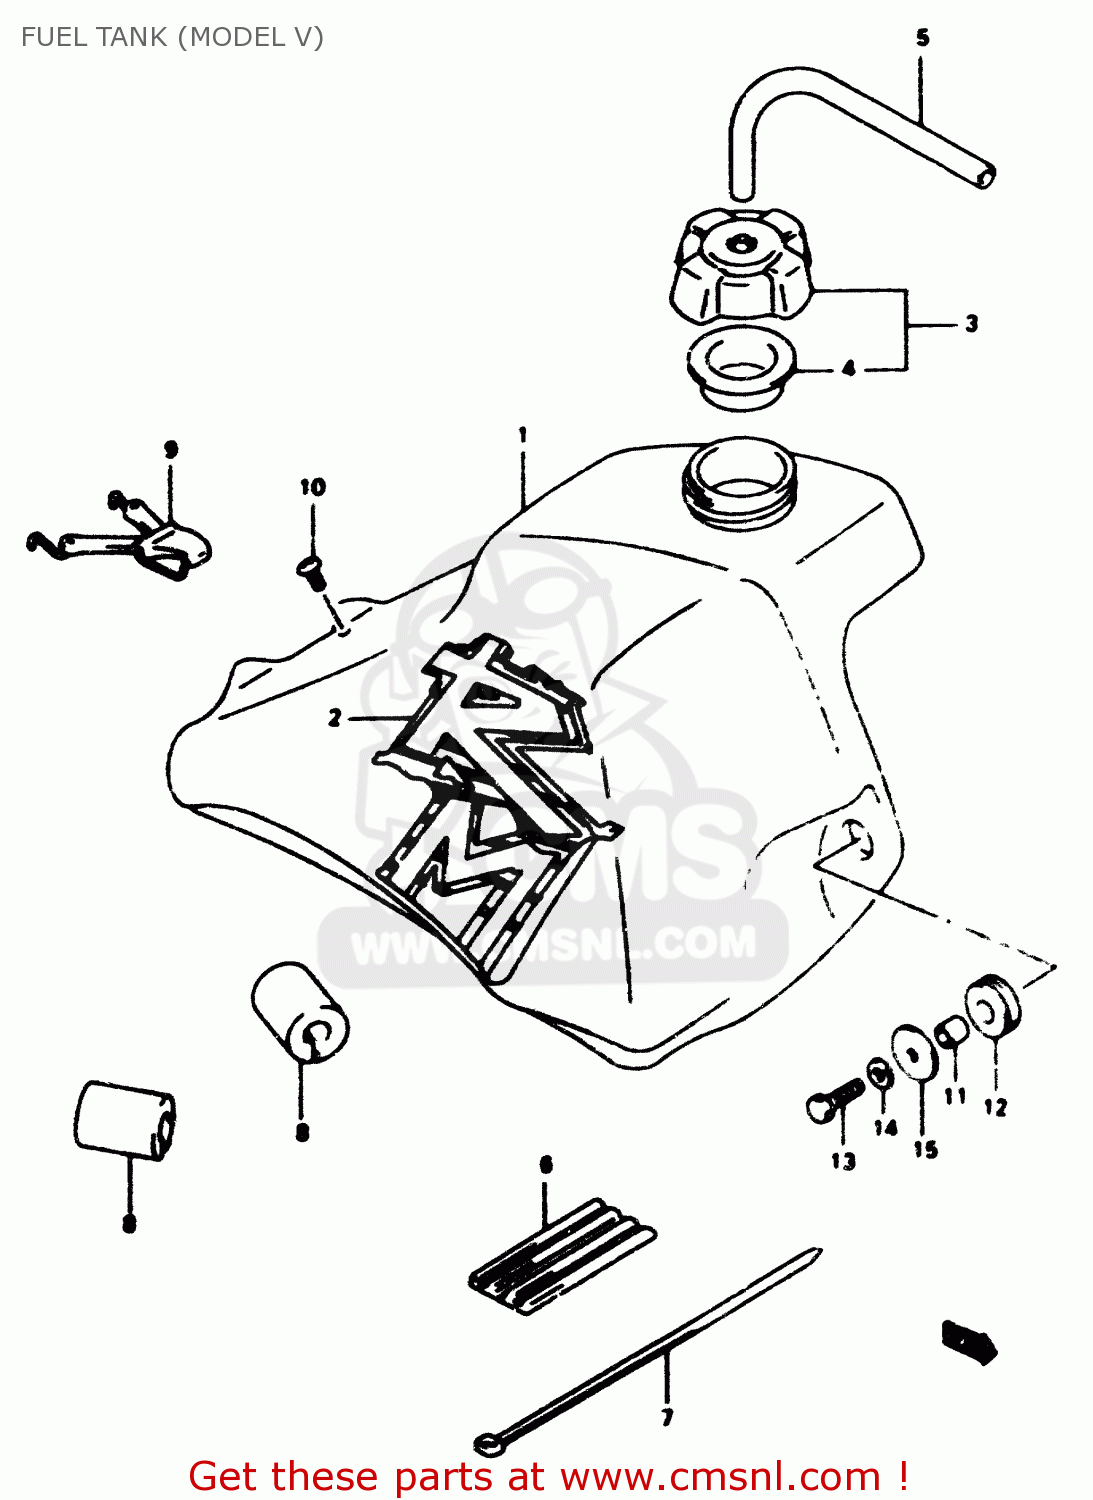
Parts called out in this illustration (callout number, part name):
1	TANK,FUEL(YELLOW)
2	EMBLEM,FUEL TANK
3	CAP SET,FUEL TANK
4	GASKET,CAP (NAS)
5	HOSE(5X8.2X600)
6	CUSHION,FUEL TANK UPR FR
7	CLAMP(L:250)
8	CUSHION,FUEL TANK UPR RR
9	BAND,FUEL TANK RR
10	SCREW
11	SPACER(6.5X10X11.5)
12	CUSHION
13	BOLT
14	LOCK WASHER
15	WASHER (6.5X24X1.6)
